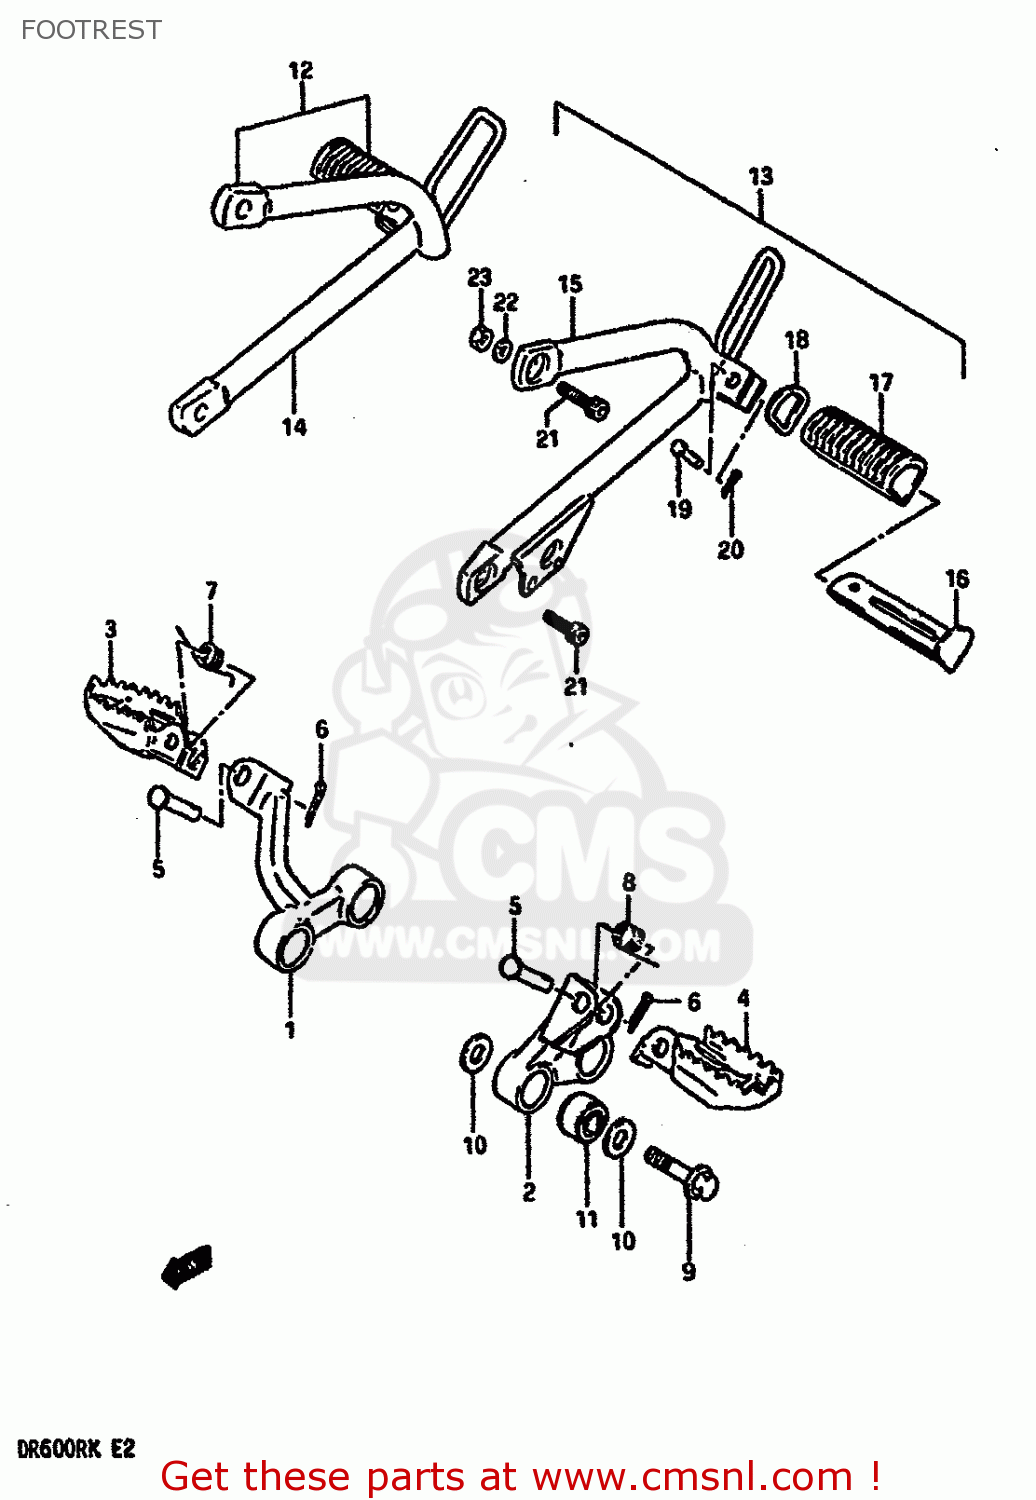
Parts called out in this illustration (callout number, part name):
1	BAR, FOOTREST RH (BLUE)
2	BAR, FOOTREST LH (BLUE)
3	FOOTREST, FRONT RH (BLUE)
4	FOOTREST, FRONT LH (BLUE)
5	PIN
6	PIN 20X20
7	SPRING
8	SPRING
9	BOLT(10X50)
10	WASHER
11	BUSH(10.2X25X19)
12	FOOTREST, PILLION RH (BLUE)
13	FOOTREST, PILLION LH (BLUE)
14	HOLDER, RH (BLUE)
15	HOLDER, LH (BLUE)
16	BAR COMP,PILLION FOOTREST
17	RUBBER,PILLION FOOTREST
18	WASHER,PILLION FOOTREST
19	PIN
20	PIN
21	BOLT
22	WASHER,LOCK,8.
23	NUT
